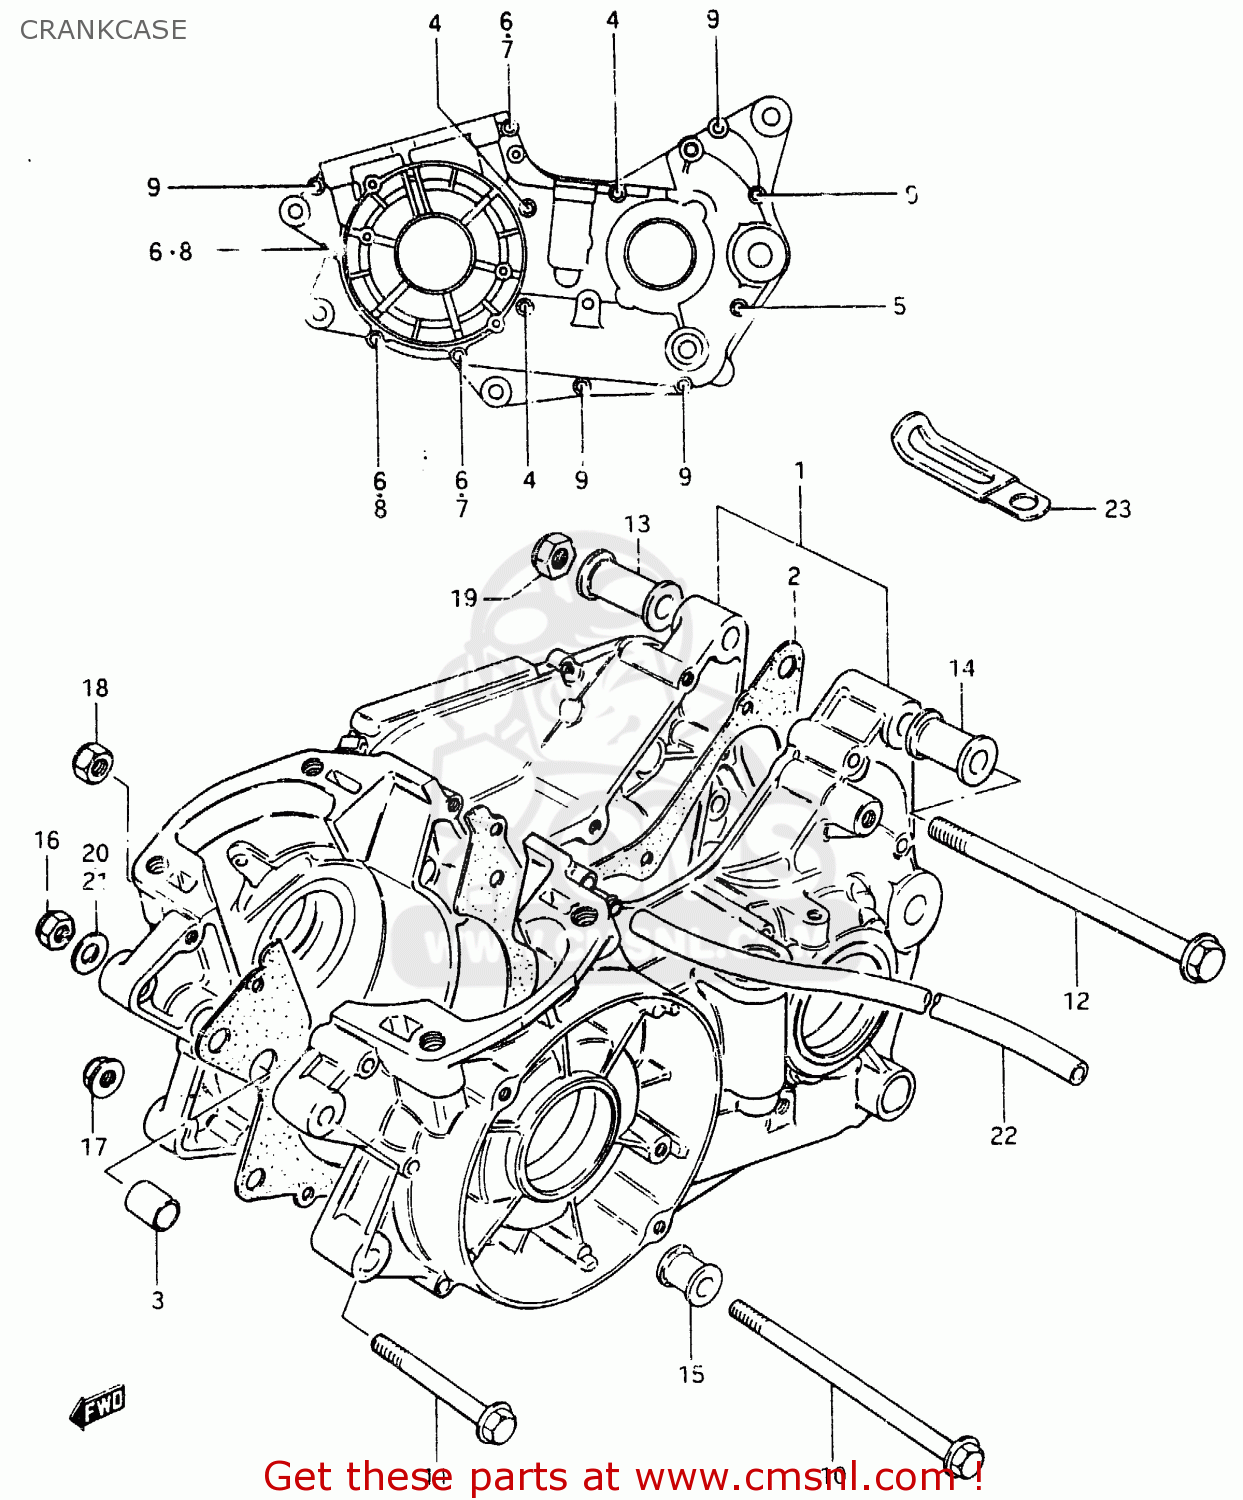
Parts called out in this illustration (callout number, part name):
1	CRANKCASE SET
2	GASKET,CRANKCASE (MCA)
3	PIN
4	SCREW 6X65
5	SCREW
6	SCREW (6X45)
7	SCREW (6X45)
8	SCREW
9	SCREW (6X35)
10	BOLT
11	BOLT(8X75)
12	BOLT 10X215
13	SPACER,ENGINE MOUNT
14	SPACER,ENGINE MOUNT
15	SPACER,ENGINE MOUNT
16	NUT
17	NUT
18	NUT
19	NUT
20	WASHER
21	WASHER
22	HOSE
23	CLAMP
